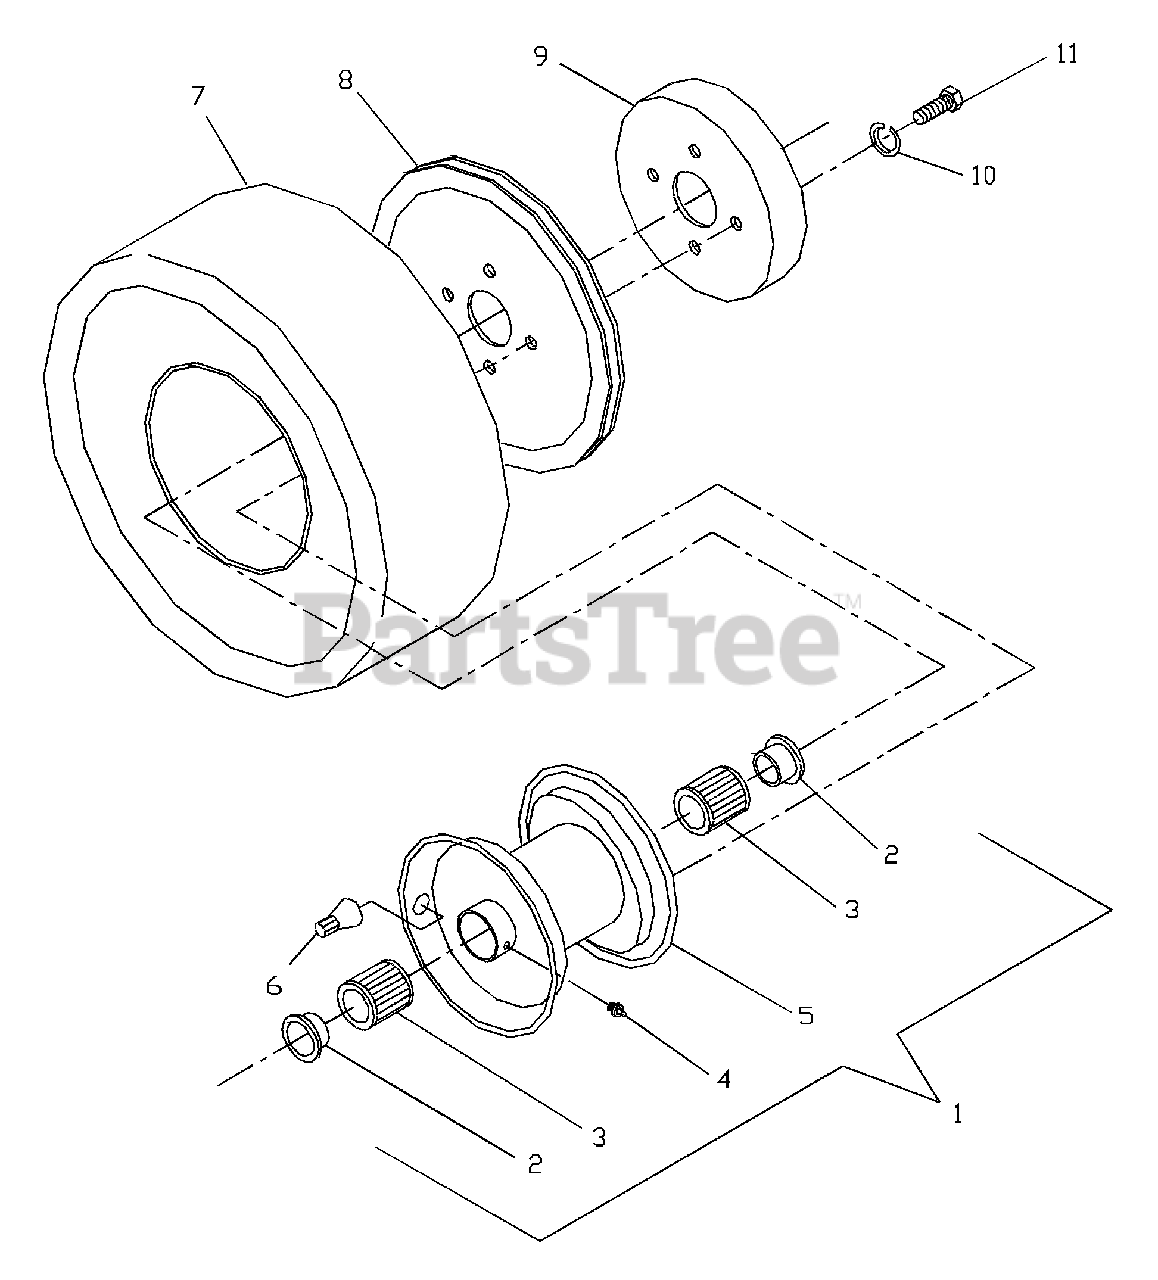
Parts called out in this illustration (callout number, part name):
1	WHEEL ASM.
3	ROLLER BEARING
4	ZERK 1/4-28 STRHT
5	RIM
8	TRACTION PULLEY
9	BRAKE DRUM
10	SLW 3/8 STD
11	HCS 3/8F X 3/4
